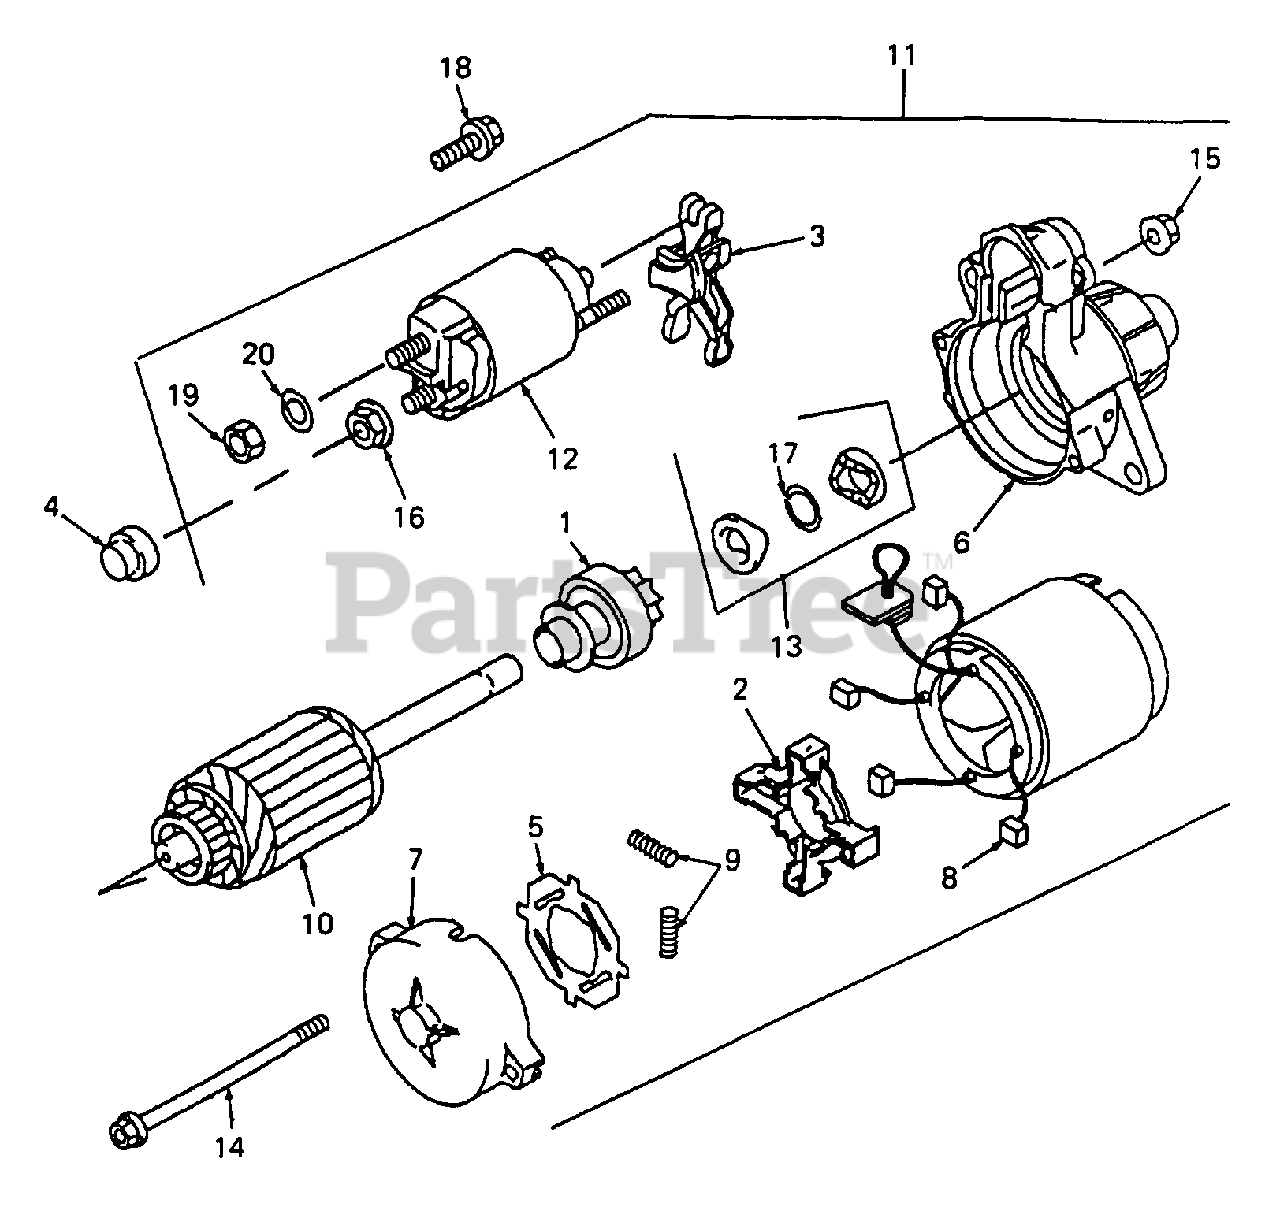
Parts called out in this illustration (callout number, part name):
2	Holder, Brush
9	Spring, Brush
11	Starter Complete
12	Switch, Solenoid
13	Stopper
18	Bolt, Flanged
19	Nut, Hex, 8 MM
20	Washer, Spring, 8 MM
